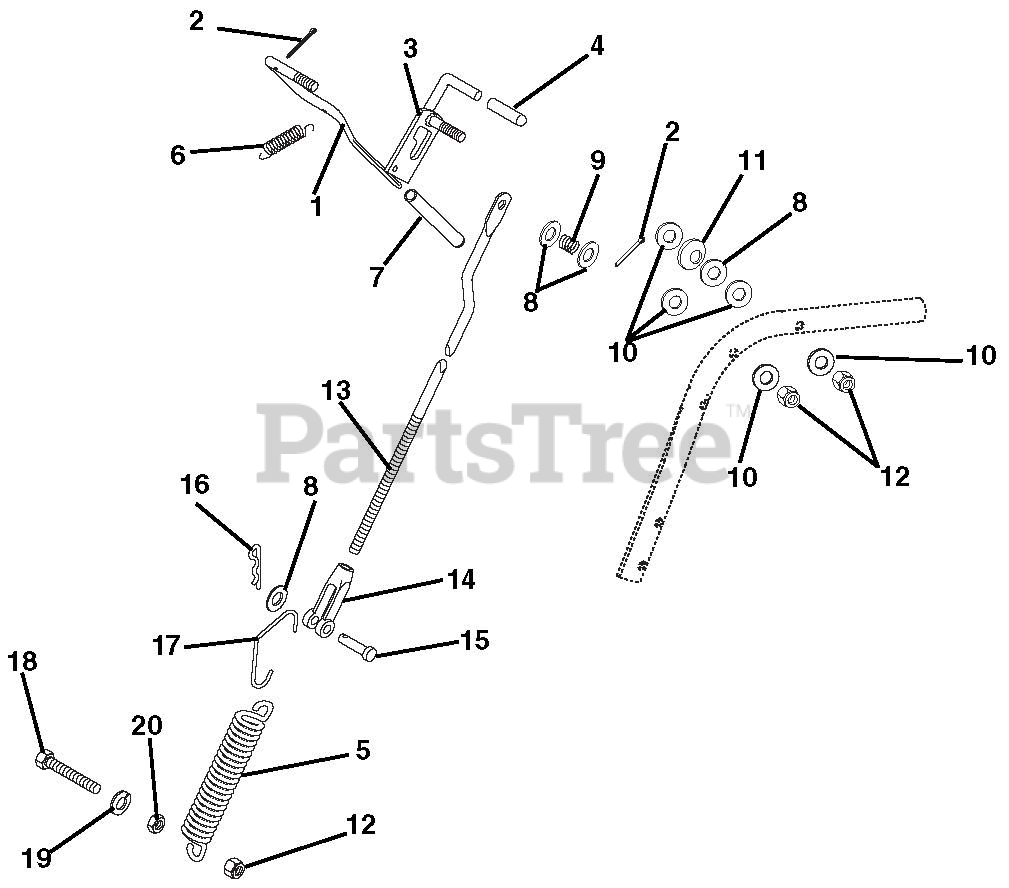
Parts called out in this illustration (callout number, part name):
1	Lever-Hand Control
1	Lever, Hand Control
2	Pin-Cotter .09 x .75
3	Weldment-Neutral Locking Lever
4	Tip-Brake Lock Lever
5	Spring-Tension .105 x 1.00 x 4.50
6	Spring-Tension .041 x .500 x 1.75
7	Grip-Hand Clutch Lever
8	Washer-Flat-Steel .406 x .812 x .065
9	Spring-Compression .045 x .600 x .750
10	Washer-Flat-Nylon .375 x .75 x .06
11	Washer-Spring .375 ID
12	Nut-Jam .38-16
12	Nut-Locking-Center .38-16
13	Rod-Pump Control
14	Clevis .38-24 Adjustable
15	Pin-Clevis .38 x 1.25
16	Pin-Hair Internal .08 x .18 x 1.18
17	Hook, Spring
18	Bolt-Hex .38-16 x 2.50 Grade 5
19	Washer-Lock .38 x .094
20	Nut-Hex .38-16
